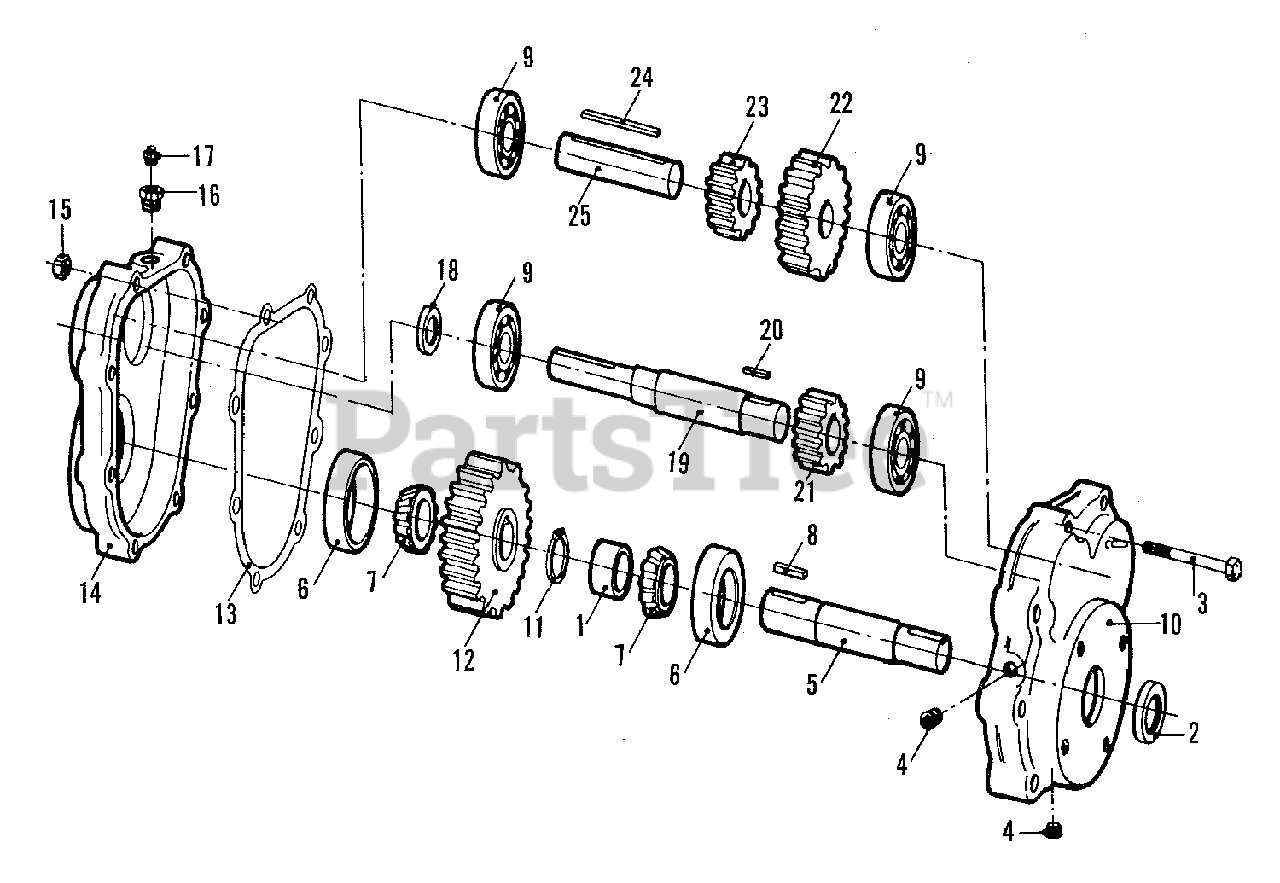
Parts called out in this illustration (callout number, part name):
1	SPACER, Collar
2	SEAL, Output
3	CAPSCREW, 5/16NC x 3
4	PLUG, Allen Head, 3/8NPT
5	SHAFT, Output
6	CUP, Bearing
7	CONE, Bearing
9	BEARING, Roller Shaft
10	HOUSING, Output Shaft
11	RING, Snap, Retaining
12	GEAR, Ouput
13	SHIM, Gasket
14	HOUSING, Input Shaft
15	NUT, 5/16NC
16	BUSHING, Reducer, 3/8NPT x 1/8NPT
17	BREATHER ASSEMBLY, 1/8NPT
18	SEAL, Input
19	SHAFT, Input
21	GEAR, Input
22	GEAR, Mid Shaft Large
23	GEAR, Mid Shaft (Small)
24	KEY, Mid Shaft
25	SHAFT, Piston (Mid)
